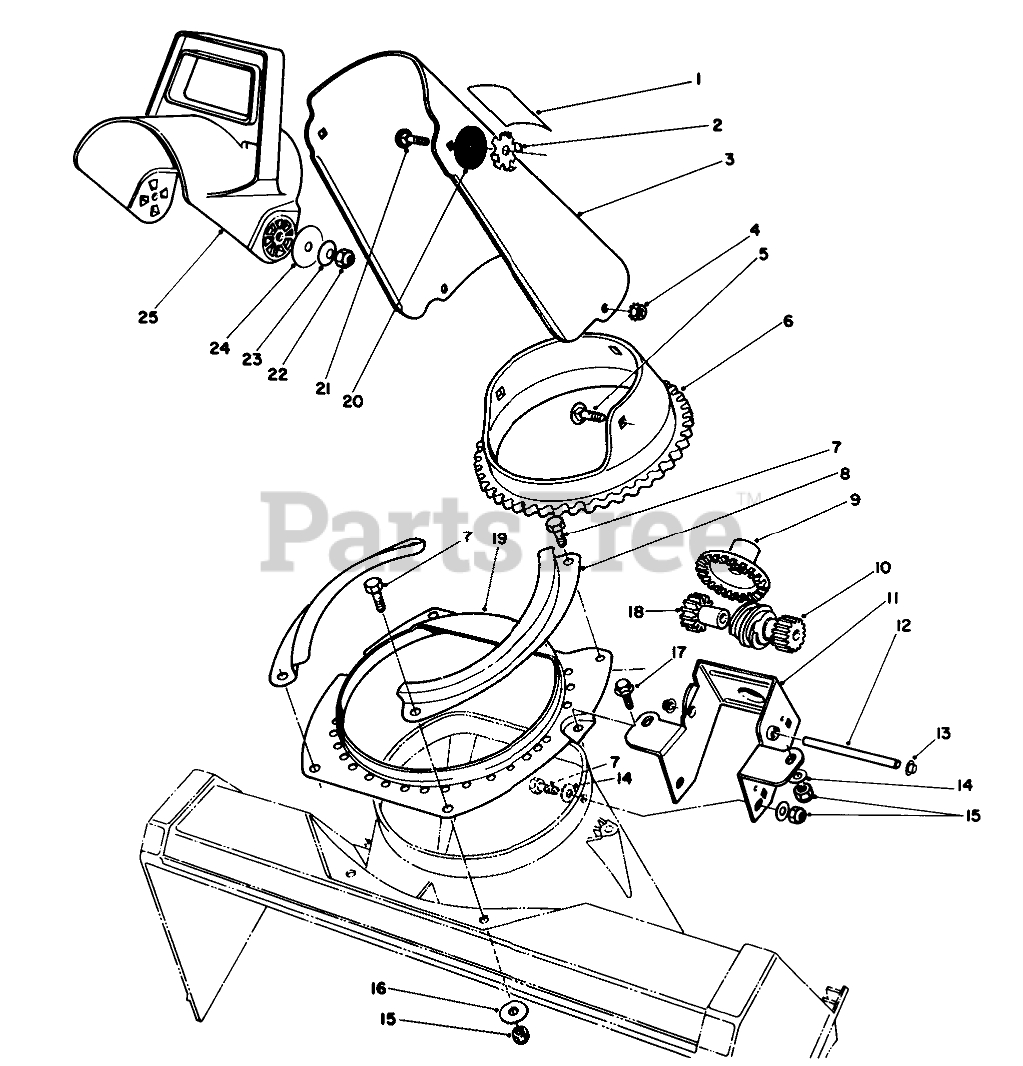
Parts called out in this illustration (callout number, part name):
1	Decal-Danger
2	PLATE-FRICTION
3	Chute-Discharge (Incl. Ref. #1:63-3760)
4	NUT-KEPS
5	SCREW-CARR
6	RING-GEAR, CHUTE
7	SCREW-HH
8	Retainer-Chute Ring
9	GEAR-FACE
10	GEAR-SPUR/WORM
11	Bracket-Chute Gear
12	SHAFT-GEAR, WORM
13	NUT-PUSH
14	WASHER-FLAT
15	NUT-LOCK, NI
16	WASHER-FLAT
17	SCREW-PLASTITE
18	GEAR-SPUR, SPACER
19	Ring-Chute Support
20	WASHER-RUBBER
21	SCREW-CARR
22	NUT-LOCK, NI
23	WASHER-BELLEVILLE
24	WASHER-FLAT
25	CHUTE-DEFLECTOR
